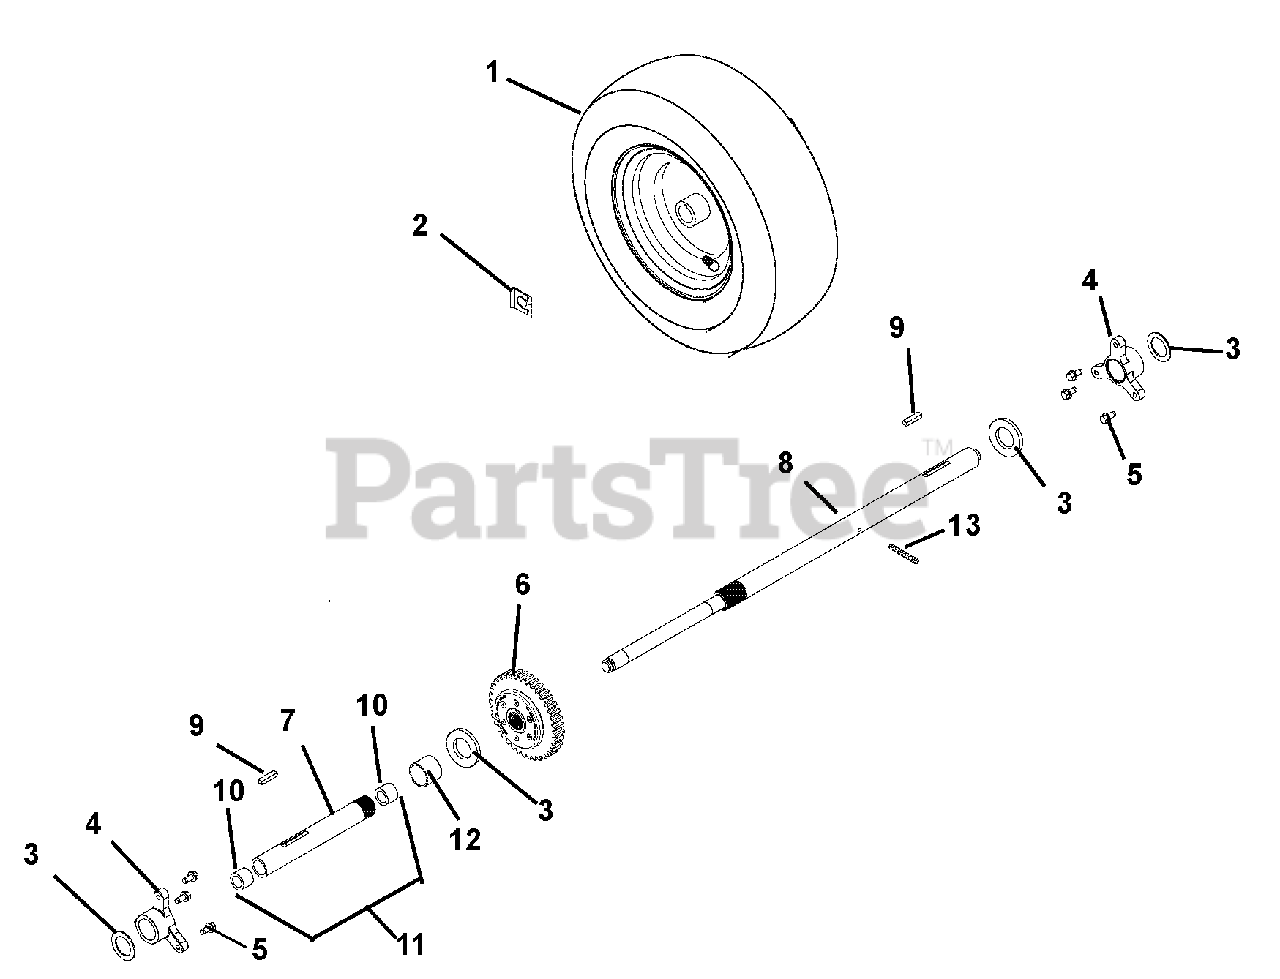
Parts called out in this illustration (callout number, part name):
1	Tire/Wheel Assembly RH 15 x 5.00 - 6 Remote
2	Clip, Snap
3	Washer, Flat Steel 1.010 x 1.505 x .062
4	Bushing, Axle
5	Screw, Tapping Hex Washer Head .25-20 x .50
6	Differential Assembly
7	Axle, Short - Differential
8	Axle, Long - Differential
9	Key Rectangular .25 x .188 x 1.00
10	Bushing, Sleeve Bronze
11	Axle, Differential with Bushings (Includes 7 and 10)
12	Bushing, Sleeve
13	Pin, Roll .188 x 1.25
